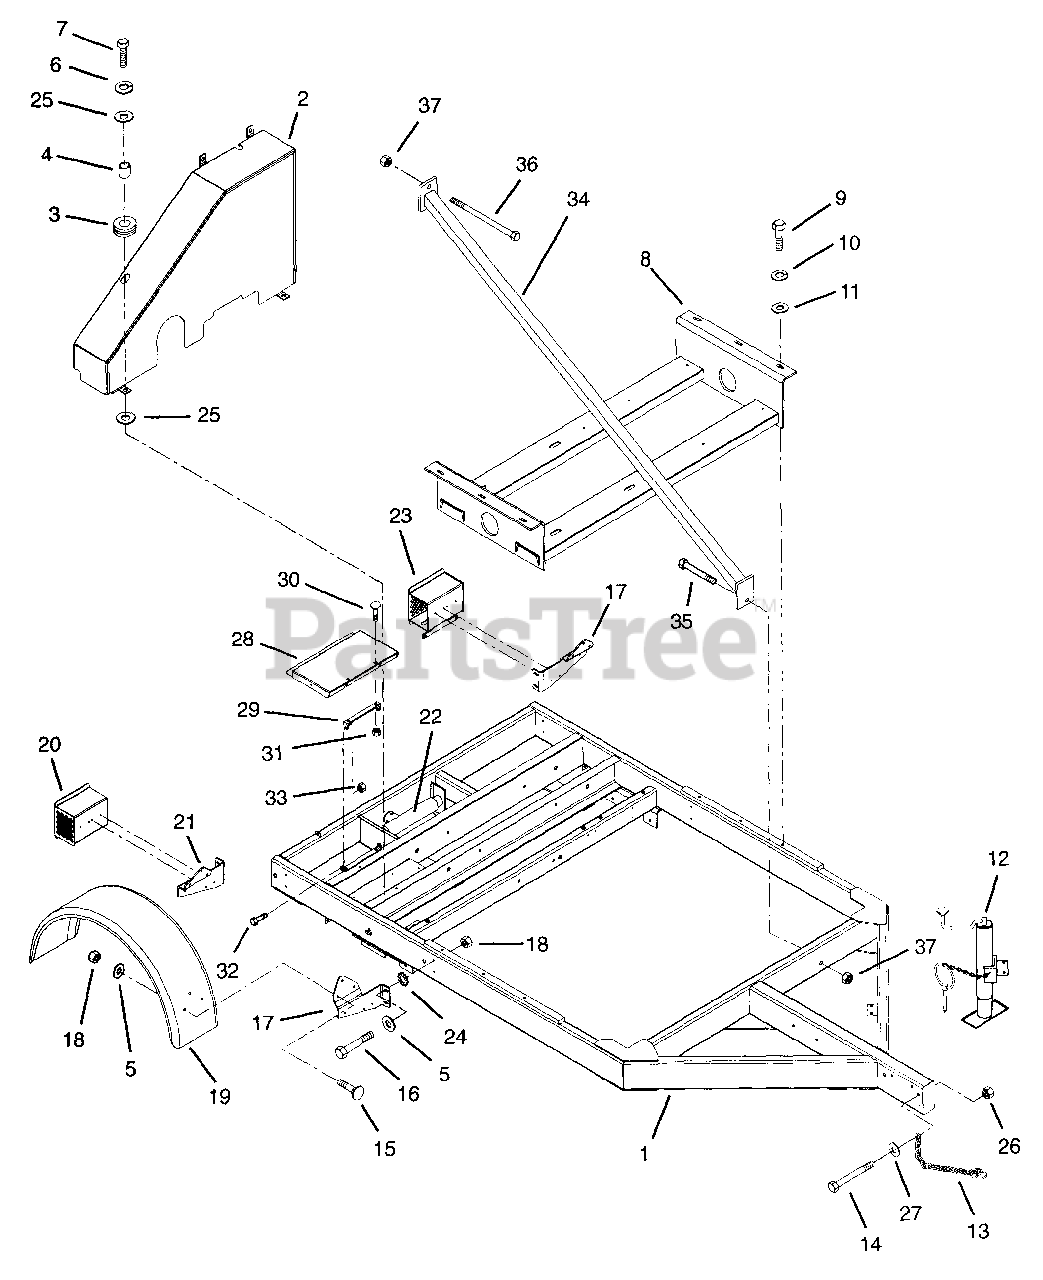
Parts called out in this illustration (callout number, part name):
1	Frame Weldment
2	Weldment-Belt Guard
3	Grommet .188 x .500
5	Washer-Flat-Steel .38 x .875 x .083
6	Washer-Lock .38 x .094
7	Bolt-Hex .38-16 x 1.25 Grade 5
8	Engine Base Weldment
9	Bolt-Hex .50-13 x 1.25 Grade 5
10	Washer-Lock .50 x .125
11	Washer-Flat-Steel .563 x 1.38 x .109
13	Safety Chain
14	Bolt-Hex .44-14 x 5.00 Grade 5
15	Bolt-Round Head Square Neck .31-18 x .75
16	Bolt-Hex .31-18 x 2.75 Grade 5
17	Fender Bracket-Left Hand
18	Nut-Locking-Center .31-18
19	Fender
20	Tail Light Bracket Weldment
21	Fender Bracket Right Hand
23	Left Hand Tail Light Bracket Weldment
24	Washer-Locking-External .326 x .599 x .031
25	Washer-Flat-Steel .39 x 1.5 x .125
26	Nut-Locking-Center .44-14
27	Washer-Flat-Steel .50 x 1.25 x .083
28	Tool Box Lid
29	Bracket -Chute
30	Bolt Round Head Square Neck .38-16 x .75
31	Nut-Locking-Center .38-16
32	Bolt-Hex .25-20 x .75 Grade 5
33	Nut-Locking-Center.25-20
34	Brace-Housing Weldment
35	Bolt-Hex .50-13 x 3.00 Grade 5
36	Bolt-Hex .50-13 x 9.00 grade 5
37	Nut-Locking-Center .50-13
